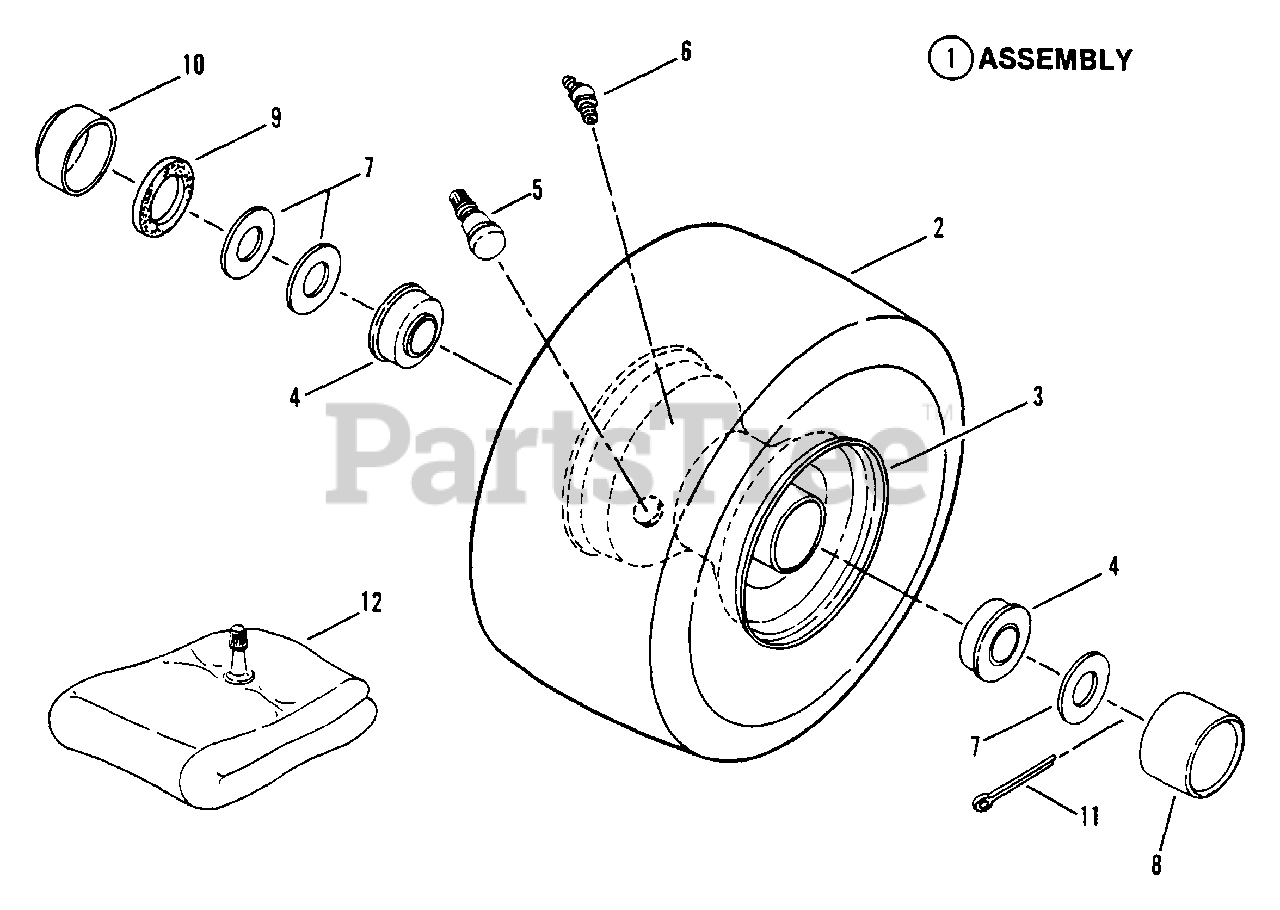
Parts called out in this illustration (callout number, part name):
1	ASSEMBLY, Tire & Rim
2	TIRE, 4.10/3.50 x 4
2A	TIRE 11:00 4:00 x 4
3	RIM
4	BEARING, Ball
5	VALVE, Air (Snap-in)
6	FITTING Lube
7	WASHER
8	CAP, Hub
9	SEAL, Felt
10	CAP, Dust
11	PIN, 5/32 x 1" Cotter Hair
12	TUBE, Inner
